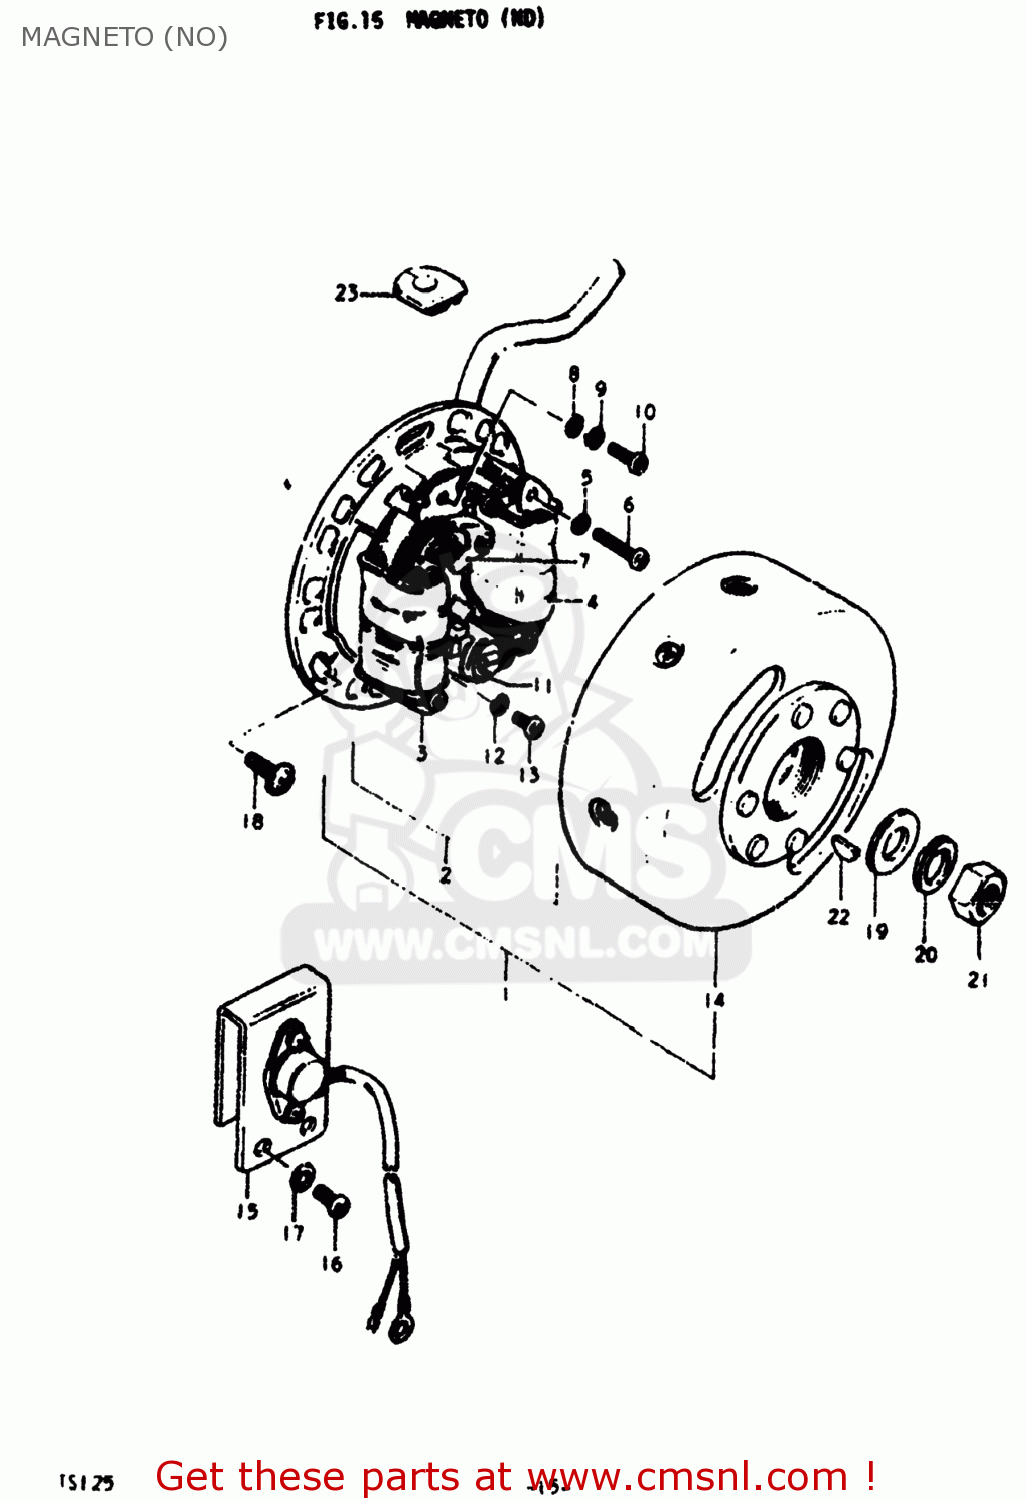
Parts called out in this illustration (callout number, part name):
1	MAGNETO ASSEMBLY
2	STATOR ASSEMBLY
3	COIL,LIGHTING
4	COIL
5	LOCK WASHER
6	SCREW 4X25
7	POINT ASSY,CONTACT
8	WASHER
9	LOCK WASHER
10	SCREW(4X10)
11	CONDENSER
12	LOCK WASHER
13	SCREW 4X10
14	ROTOR ASSEMBLY
15	REGULATOR ASSEMBLY
16	SCREW 6X12
17	WASHER
18	SCREW(5X14)
19	WASHER
20	LOCK WASHER
21	NUT (10MM)
22	KEY
23	GROMMET
